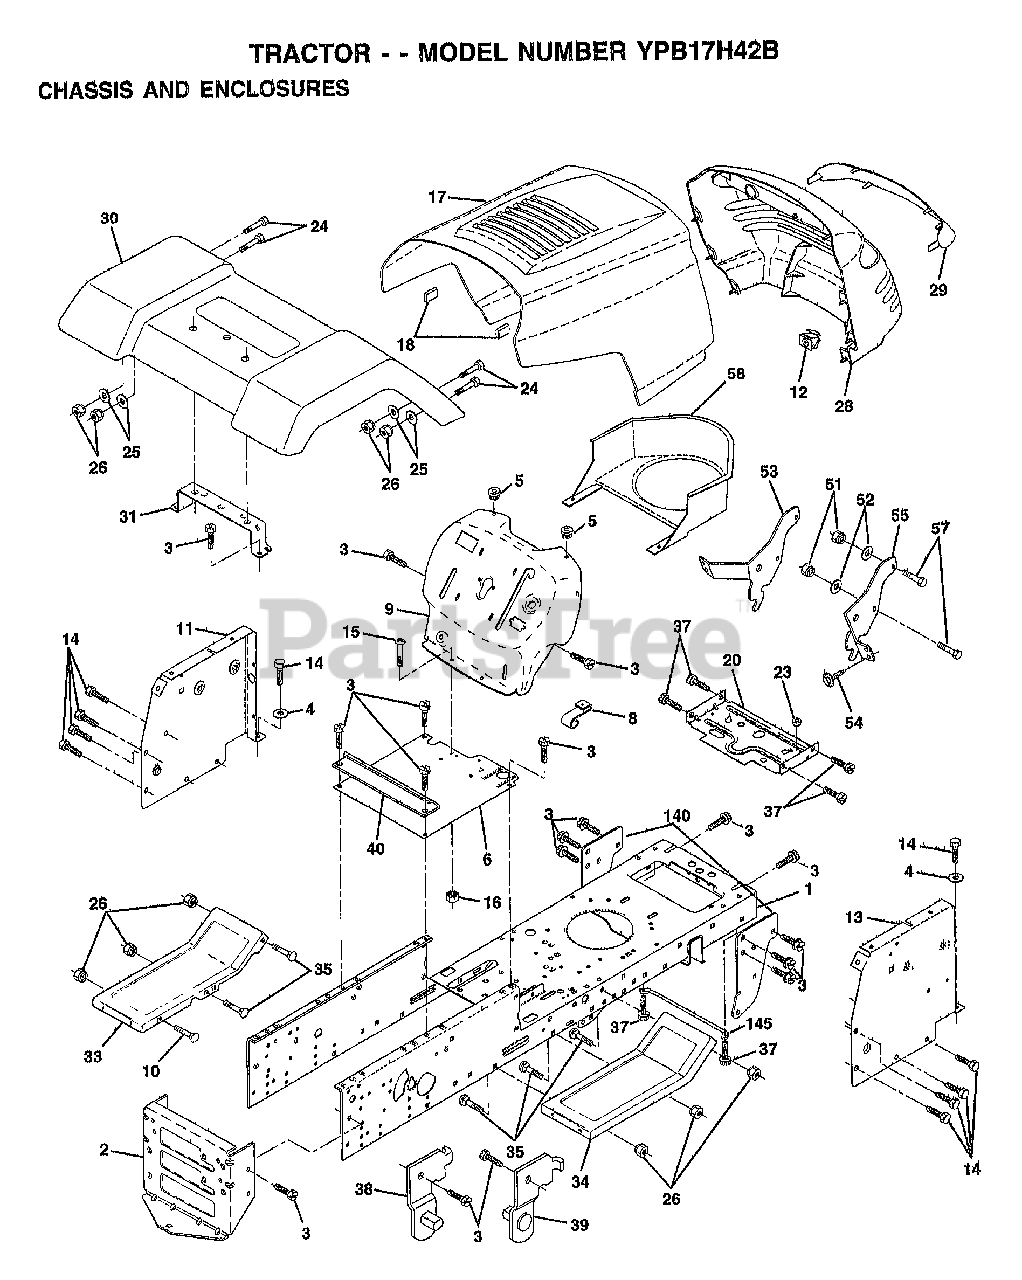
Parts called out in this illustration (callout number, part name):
1	CHASSIS.STAMPING
3	SCREW
4	WASHER
5	BUMPER-HOOD/DASH
6	SADDLE
8	CLIP.RETAINER
9	DASH.SILKSCREEN
11	"PANEL-DASH,LH"
12	CLIP.TINNERMAN
13	PANEL.ASM.DASH.RH
14	SCREW LT
15	SCREW
17	"HOOD W/TRIM,MS428"
20	"PLATE-MTG,BATT/FU"
24	BOLT
25	WASHER
26	NUT
28	GRILL
29	GRILLE.LENS
30	FENDER.LTST.WLDMNT.W/SHIFT
31	BRACKET SUPT FEND
33	FOOTREST PNT LH
34	FOOTREST.RH.LT/GT
35	BOLT
37	SCREW LT
38	BRACKET ASM LH
39	BRACKET ASM RH
40	SPACER FENDER LT
51	NUT
52	WASHER
53	BRACKET.GRILLE.LH
54	SCREW.HEX.WS.HD
55	BRACKET.GRILLE.RH
58	AIR DUCT
140	BRKT SUSPENSION
145	"ROD POVOT,CHASSIS"
